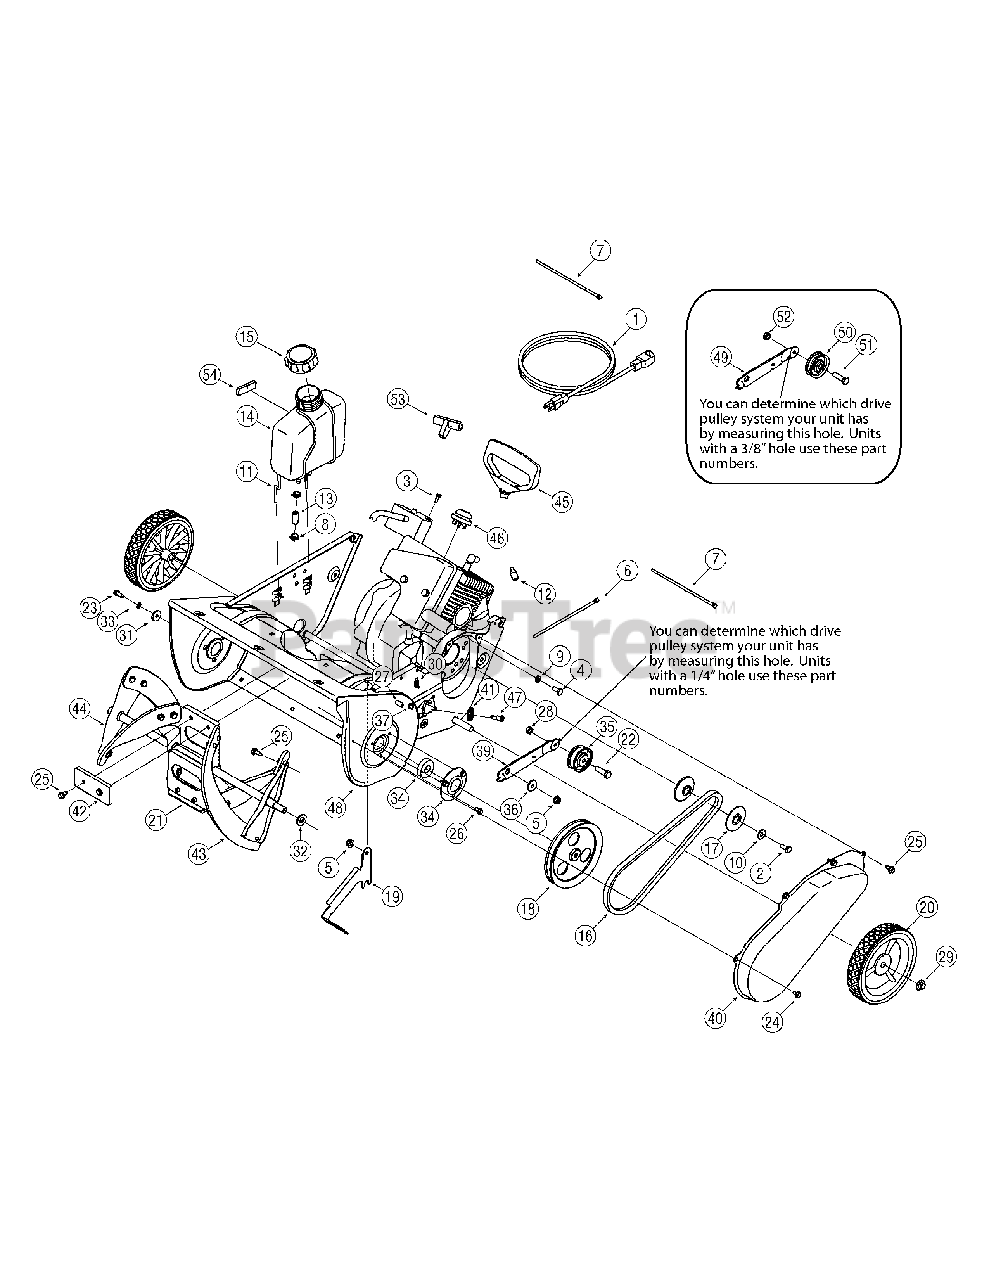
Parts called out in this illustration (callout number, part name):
1	Extension Cord
2	Hex Screw, 5/16-24 x .75
4	Hex Screw, 5/16-18 x .625
5	Hex Flange Lock Nut, 5/16-18
6	Screw, #10-16 x .625
6	Push Mount Cable Tie
7	Push Mount Cable Tie
8	Clamp, Hose
9	Washer, Lock 5/16
10	Flat Washer .349 x .879 x.063
11	Gas Tank Support Wire
12	Choke Lever Knob
13	Hose, Fuel Line
14	Tank, Fuel
15	Cap, Fuel
16	V-Belt, 1/2
17	Pulley Half, .625 ID x 2.25 OD
18	Pulley, 1/2 V 1/2-20 LH x 6.0
19	2-Cycle Mounting Bracket
20	Wheel, 7 x 1.61 Dia. Tread
21	Auger Assembly Complete
22	Hex Screw, 1/4-20 x 1.00 Gr. 5
23	Hex Screw 1/4-20 x .75 Gr. 5
24	Self-tapping Screw 1/4-20 x .375
25	Hex Screw, 1/4-14 x 0.625"
26	Self-tapping Screw, 1/4-14 x .50
27	Hex Screw 5/16-18 x .75
28	Hex Flange Lock Nut, 1/4-20
29	Push Cap, 1/2"
30	Extension Spring
31	Flat Washer .265 x .938 x .120
32	Flat Washer .510 x 1.0 x .125
33	Lock Washer, 1/4
34	Ball Bearing 17 x 40 x 12
35	Idler Pulley (Pulley hole 1/4")
36	Shoulder Spacer .25
37	Hex Lock Nut 1/4-28
38	Bearing Cup
39	Idler Brkt. w/Brake (Pulley hole 1/4")
41	Cable Roller
42	Rubber Paddle
43	Crescent Spiral
44	Auger Axle
45	Recoil Handle, Mitten (Optional)
47	Carriage Screw 1/4-28
49	Idler Brkt. w/ Brake (Pulley hole 3/8")
50	Idler Pulley (3/8" hole)
51	Hex Screw 3/8-24 x 1.25
52	Jam Lock Nut 3/8--24
53	Recoil Handle (Optional)
54	Foam Tape .625 X.25
